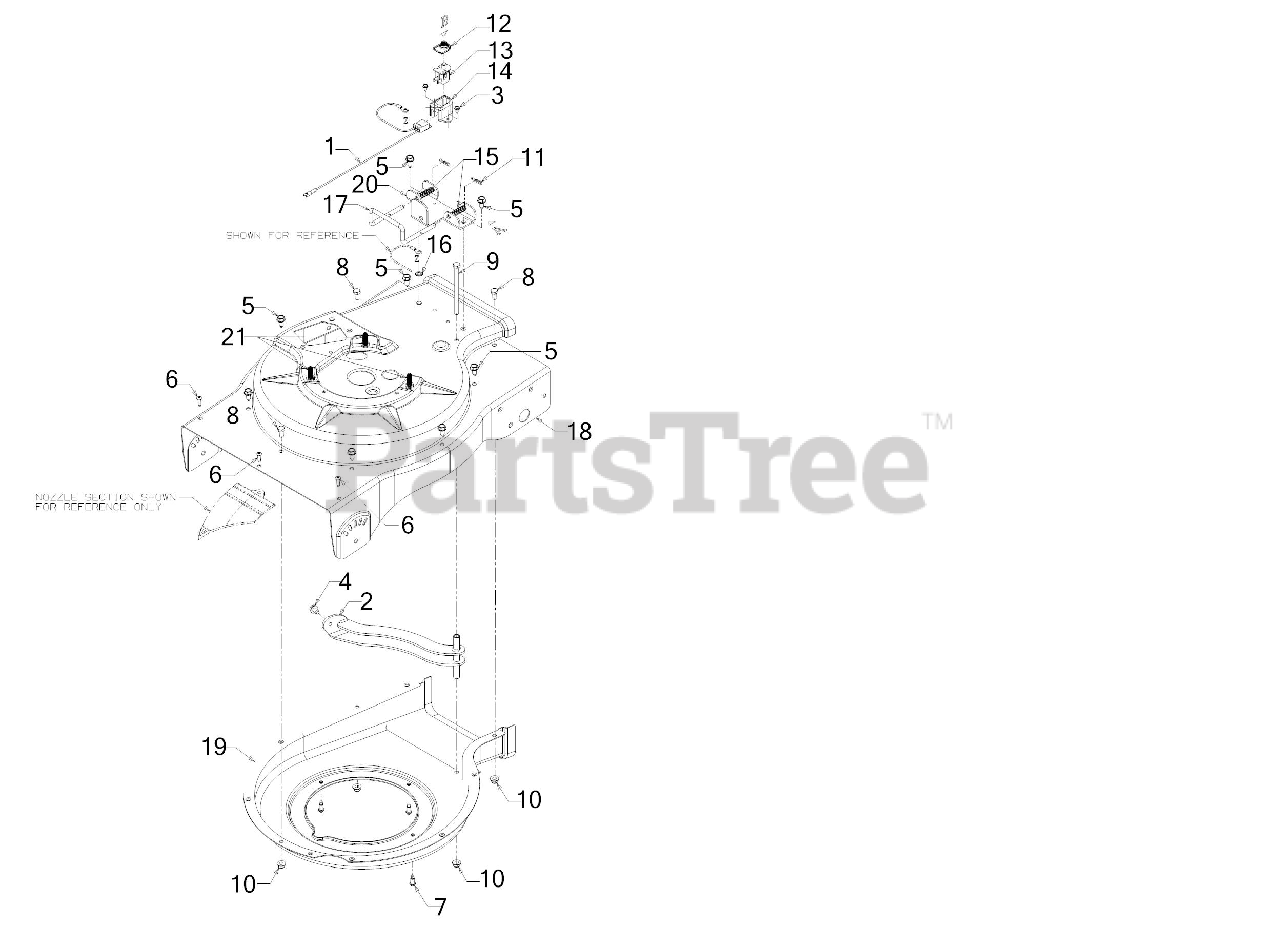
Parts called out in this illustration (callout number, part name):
1	WIRE HARNESS ASSEMBLY
2	SCREEN ASSEMBLY
3	HEX SCREW AB-TAP #10-16 x 0.500
4	SCREW 5/16-18 x .500
5	SCREW 5/16-12 x .750
6	SCREW #12-16 x .750
7	SCREW .30 x .46
8	SCREW 5/16-18X .625 GR5
9	SCREW 5/16-18 x 4.5 GR5
10	FLANGE LOCK NUT 5/16-18
11	COTTER PIN .072 DIA
12	SWITCH COVER
13	SNAP MOUNT SWITCH
14	SWITCH COVER
15	COMPRESSION SPRING
16	WASHER
17	LOCK ROD
20	MOUNTING BRACKET
21	SCREW 3/8-16 x 1
